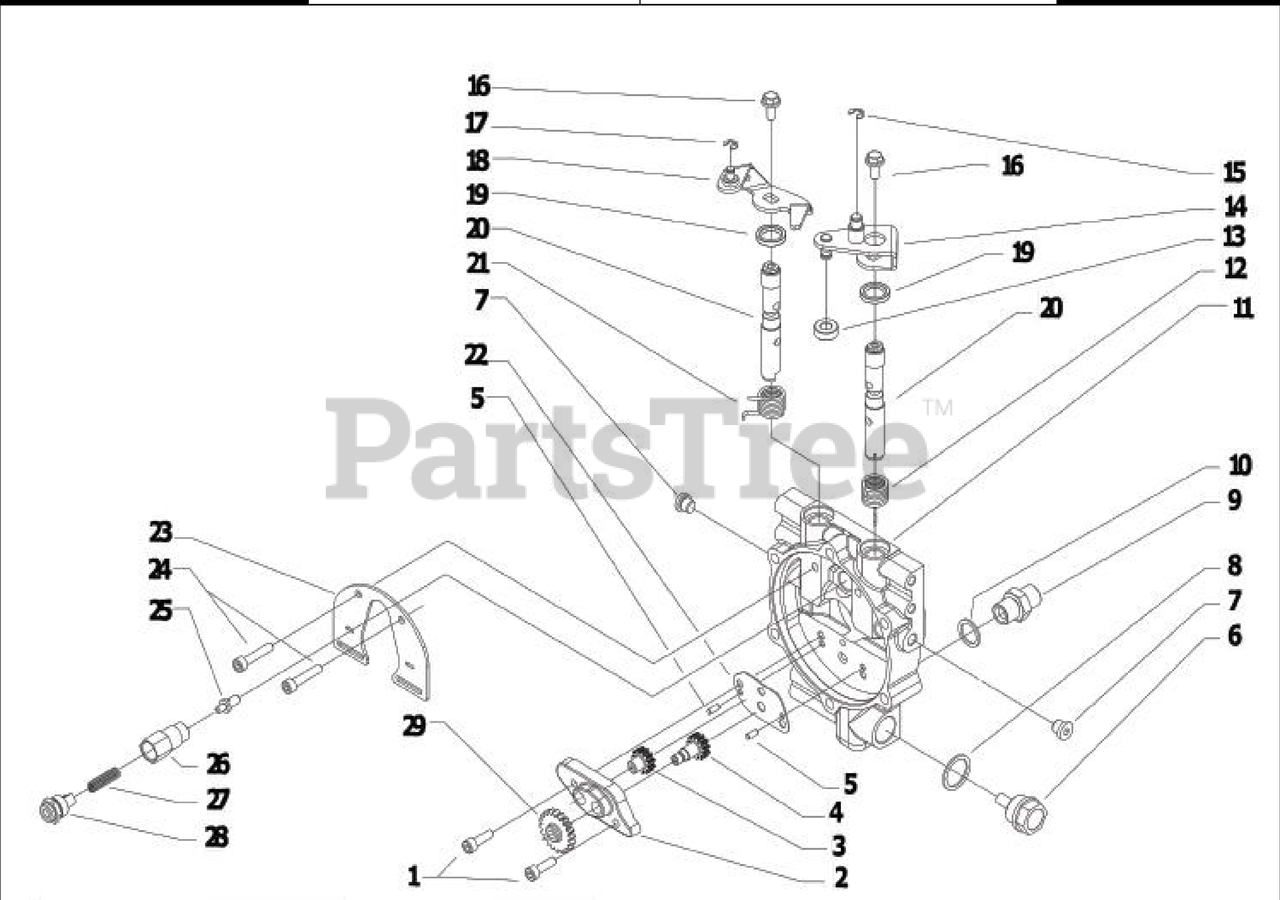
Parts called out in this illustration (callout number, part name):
1	SCREW TCEI M6X20 UNI 5931
2	PUMP COVER
3	PUMP GEAR
4	PUMP GEAR
5	CYLINDRICAL PLUG
6	PLUG
7	PLUG
8	GASKET 22X28X1.5 CU 99.5
9	NIPPLE
10	COPPER WASHER 16.7x22/1.5
11	FLANGE
12	SPRING
13	ROLLER
14	CLUTCH LEVER
15	SNAP RING E 6 UNI 7434
16	SCREW TE C/F M6X14 DIN 6921 8G
17	SNAP RING E 5 UNI 7434
18	LEVER STOP
19	OIL SEAL 14X22X4
20	CONTROL VALVE
21	SPRING
22	PLATE PUMP RECEPTOR
23	SHIELD
24	SCREW TCEI M6X30 UNI 5931
25	VALVE
26	VALVE SEAT
27	SPRING
28	PLUG
29	GEAR (LEFT HAND THREAD)
